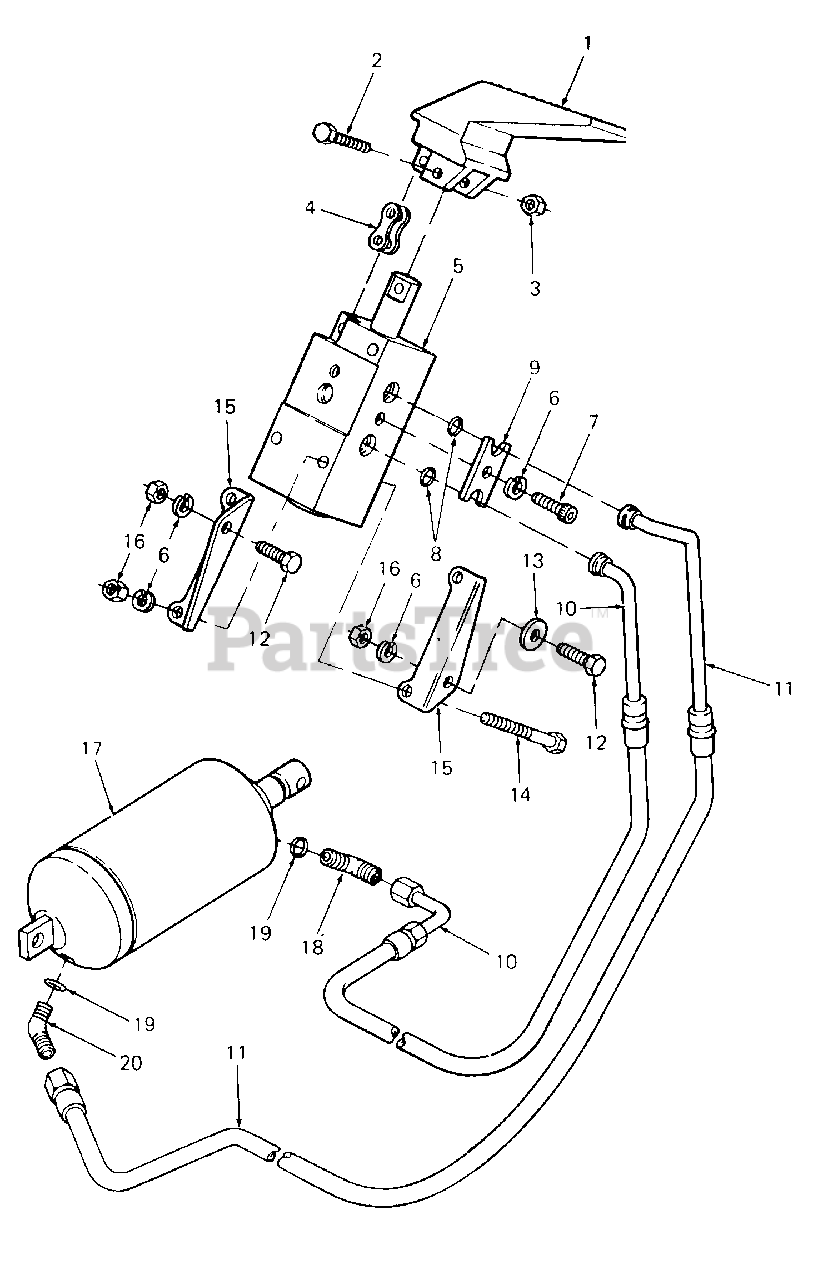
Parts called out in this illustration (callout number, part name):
1	Handle, Valve
2	Screw, Hex Cap, #10-24 X 1.0 Lg
3	Nut, Hex Center Lock, #10-24
4	Link, Chain
5	Valve, Lift
6	Washer, Lock, 1/4
7	Screw, Socket Hd Cap, 1/4-20 X .62 Lg GR8.
8	O-Ring, .301 X .070 Dia
9	Clamp, Double
10	Hose, Cylinder-Contracting
11	Hose, Cylinder-Extending
12	Screw, Hex Cap, 1/4-20 X.62 Lg GR5
13	Washer, Bell, .265 X .75 X .062 Thk
14	Screw, Hex Cap, 1/4-20 X 2.25 Lg
15	Bracket, Valve Mtg
16	Nut, Hex, 1/4-20 GR5
17	Cylinder, Hydraulic
18	Elbow, 90 Deg w/O-Ring
19	O-Ring, 1/4 OD Tube
20	Elbow, 45 Deg w/O-Ring
